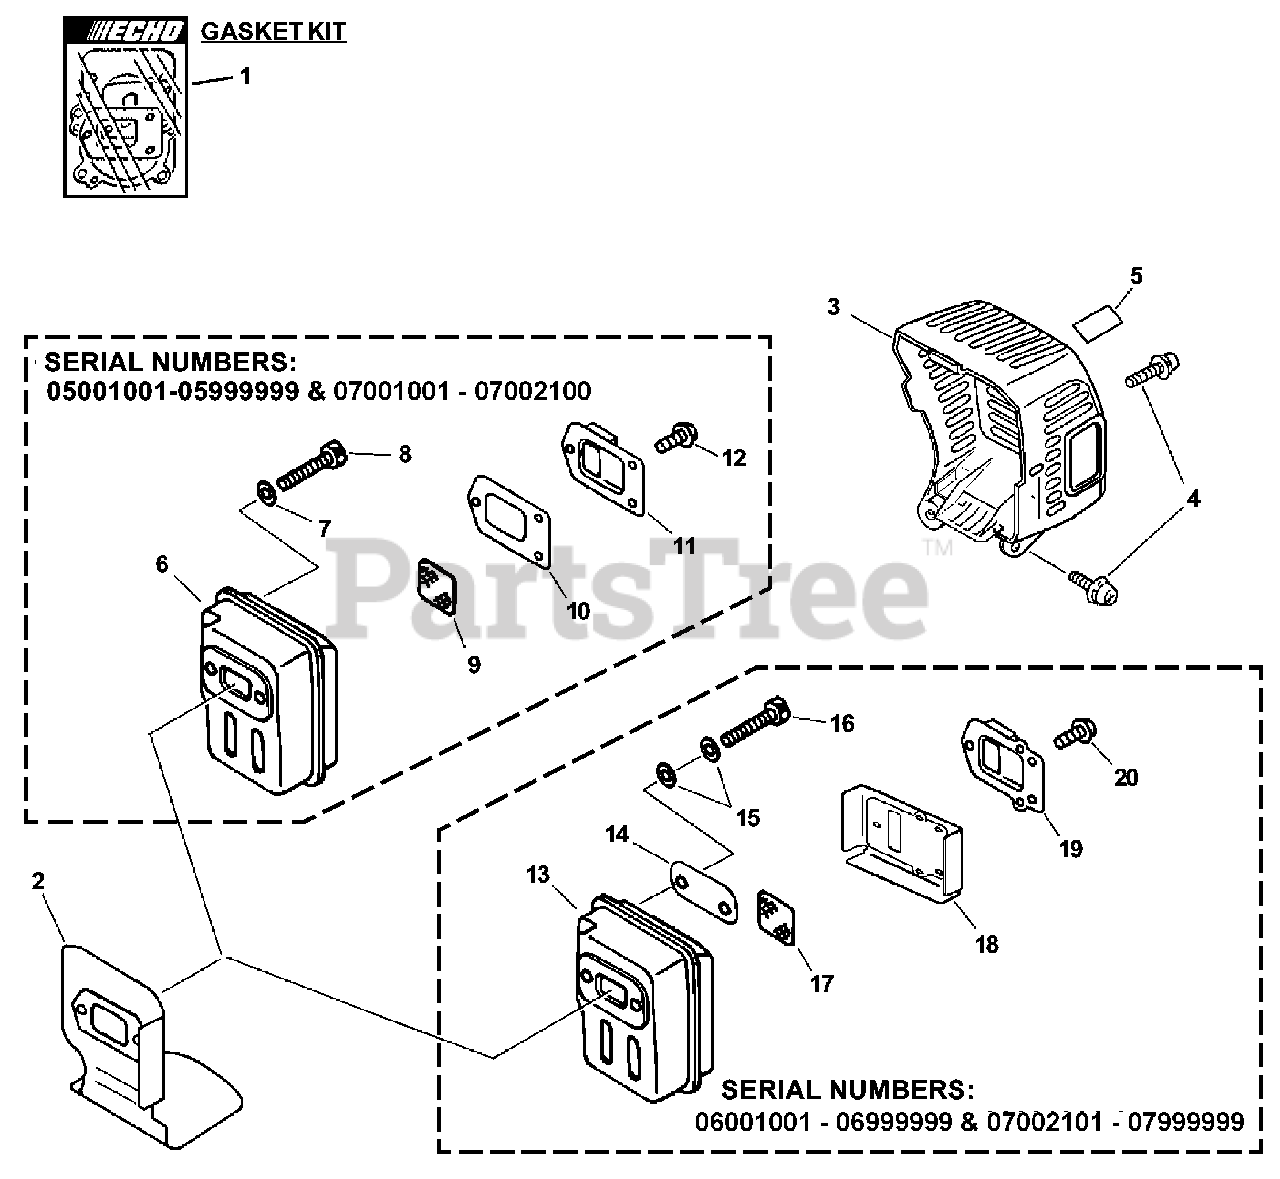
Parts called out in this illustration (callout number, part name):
1	GASKET KIT
2	SHIELD, EXHAUST
3	COVER, EXHAUST
4	SCREW - 5X12
5	LABEL - HOT SURFACE
7	WASHER - 5
8	SCREW - 5X55
9	SCREEN, SPARK ARRESTOR
10	GASKET, EXHAUST
11	GUIDE, EXHAUST
12	SCREW - 4X10
13	MUFFLER
15	WASHER - CONICAL
16	SCREW - 5X55
17	SCREEN, SPARK ARRESTOR
18	GASKET, EXHAUST
19	GUIDE, EXHAUST
20	SCREW - 4X10
